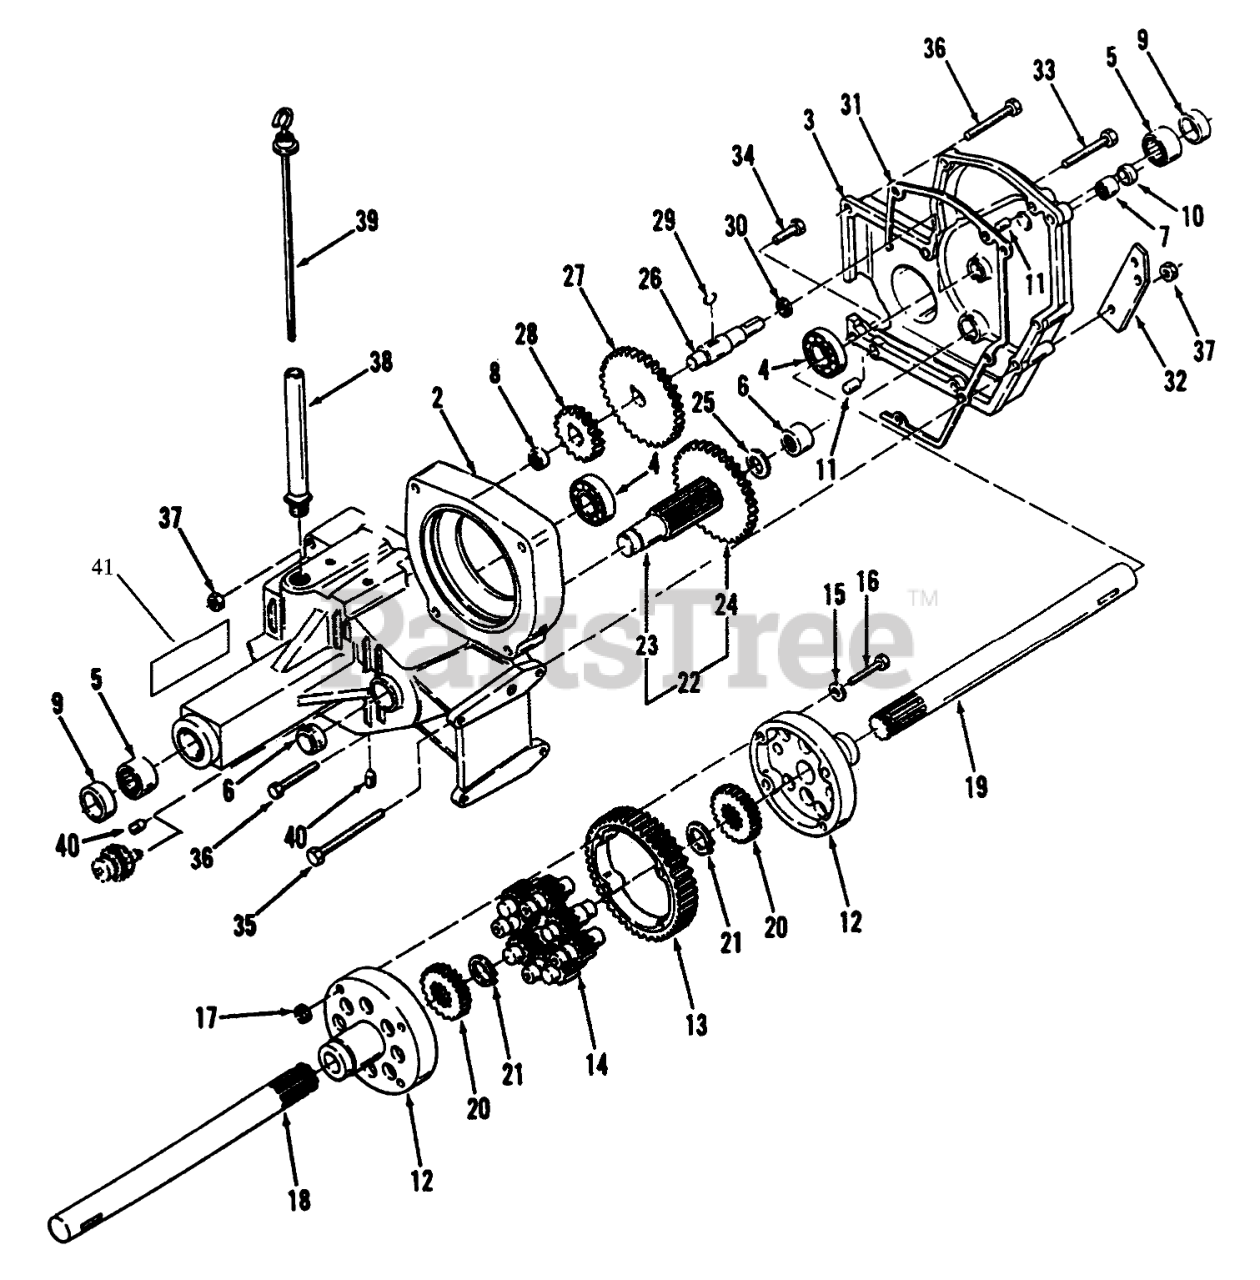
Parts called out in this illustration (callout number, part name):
1	Transaxle (Incl Ref. #41)
2	CASE-TRANSMISSION RH
3	CASE TRANS LH
4	BEARING-BALL
5	BEARING
6	BEARING-NEEDLE
7	NEEDLE BEARING
8	BEARING-NEEDLE
9	SEAL-OIL
10	Seal
11	PIN-LOCATING
12	END CAP-DIFFERENTIAL
13	GEAR-DIFFERENTIAL RING, 43T
14	GEAR-PINION, 11T
15	WASHER
16	BOLT-HEX
18	AXLE-REAR RH
19	AXLE-REAR LH
20	GEAR-AXLE DIFFERENTIAL
21	RING-SNAP
22	ASSY GEAR
23	PINION SHAFT
25	WASHER-THRUST
26	SHAFT GEAR
27	GEAR 46 TEETH
28	GEAR 20 TEETH
29	Key
30	Race Thrust
31	GASKET-TRANSMISSION
32	BRACKET-BRAKEB
33	Bolt
34	SCREW-HH
35	SCREW-HH
36	SCREW-HH
37	NUT-LOCK, NI
38	NIPPLE-TRANS FILL
39	Dipstick
41	DECAL - DANGER
